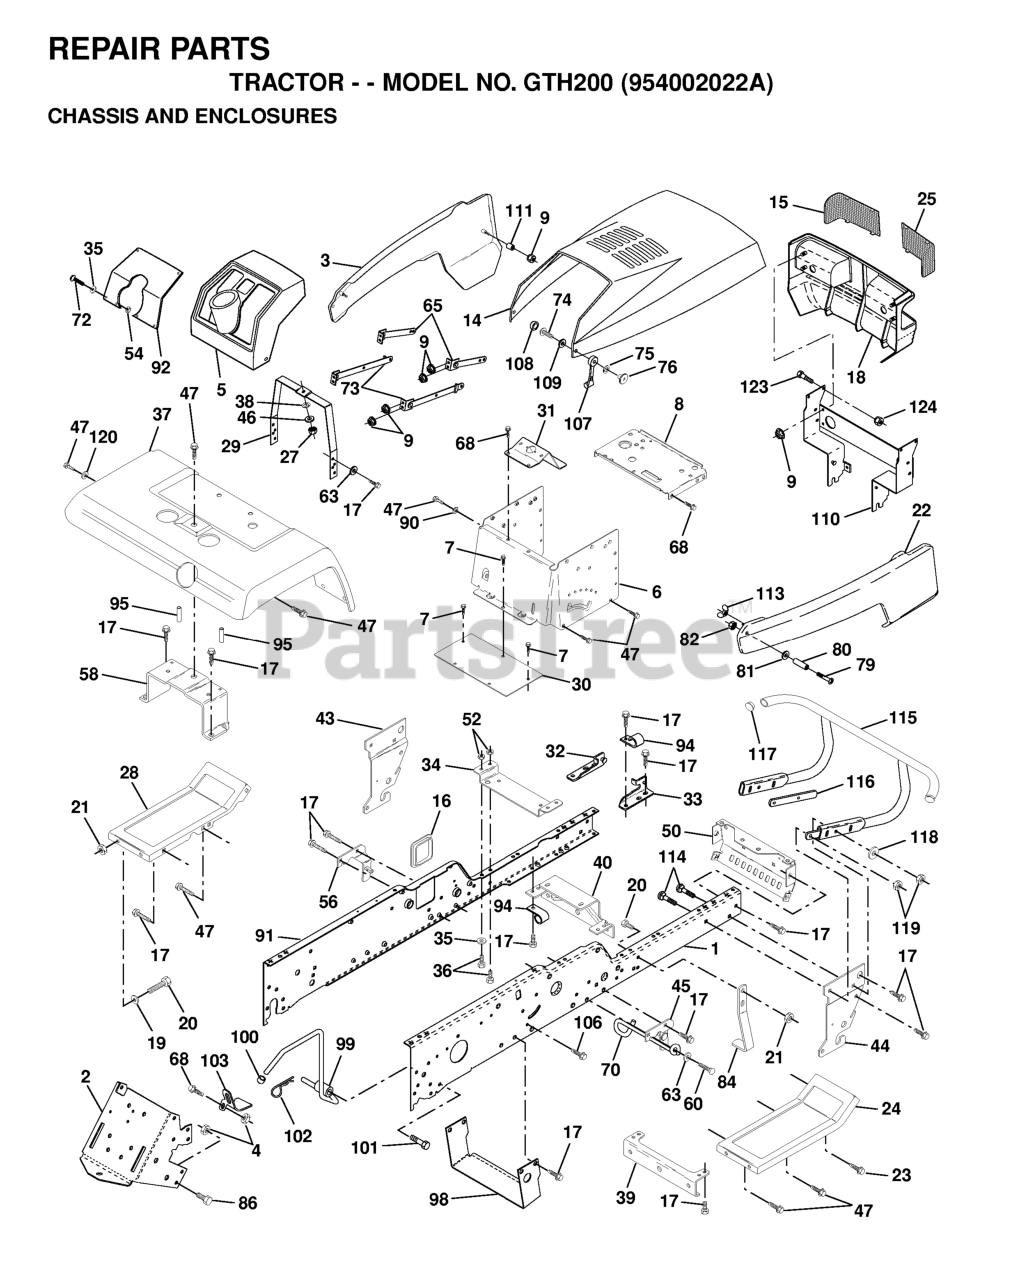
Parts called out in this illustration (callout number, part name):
1	RAIL, FRAME RH
2	DRAWBAR-GT
3	SIDE PANEL ASSY LH
4	Nut, Lock Hex 7/16 Unc
6	DASH, LOWER
7	SCREW
8	SUPPORT, BATTERY
9	PAL NUT LT
14	HOOD.HUSQVARNA.ORANGE
15	LENS RH
16	COVER ACCESS
17	SCREW
18	GRILL COMPLETE
19	WASHER
20	BOLT
21	NUT
22	SIDE PANEL ASSY RH
24	FOOTREST RH
25	LENS LH
27	NUT
28	FOOT REST LH
29	DASH SUPT YP
30	SADDLE.HYDRO.95
31	BRACE, SUPPORT STEERING
32	FRAME PIVOT BRKT ASSY LH
33	FRAME PIVOT BRKT ASSY RH
34	ENGINE SUPPORT BRKT
35	WASHER
36	BOLT.FIN.HEX.5/16-18X3/4
37	FENDER
38	LOCKWASHER
39	FRONT AXLE BRACKET
40	AXLE SUPPORT BRKT
43	FRONT SUSPENSION BRKT LH
44	FRONT SUSPENSION BRKT RH
45	CHASSIS BRKT
50	CHASSIS BRKT
52	NUT.71038.31-18.HEX.NYLOCK
54	NUT
56	SUSPENSION BRKT LH
58	FENDER BRKT
60	SCREW
63	WASHER
68	Screw 5/16-18 x 1/2 Hex, Self Tapping 5/16-18 x 1/2
70	BELT GUIDE
72	Screw, Machine, Truss Head 5/16-18 UNC x 3/4
74	SCREW
75	LOCKWASHER #10
76	WELDNUT
79	RP SCREW
82	NUT **
84	MOWER STOP
86	BOLT
90	LOCKWASHER
91	RAIL, FRAME LH
92	DASH PLATE
95	NUT-PUSH YT
98	BRACKET CHASSIS
99	ROD ASMBLY BYPASS
100	CAP
101	SCREW LT
102	RETAINER M
103	BRACKET LOCK BYPASS
106	SCREW
107	LATCH.HOOD.
108	SNAP CAP LT
110	GRILL SUPPORT ASSY
113	WING NUT
114	BOLT.3/8-14X1.25
115	BUMPER ASSY
116	BRACKET BUMPER
117	PLUG PLASTIC
118	WASHER
120	WASHER
123	BOLT T
124	LOCKNUT.NYLOC.1/4-20
